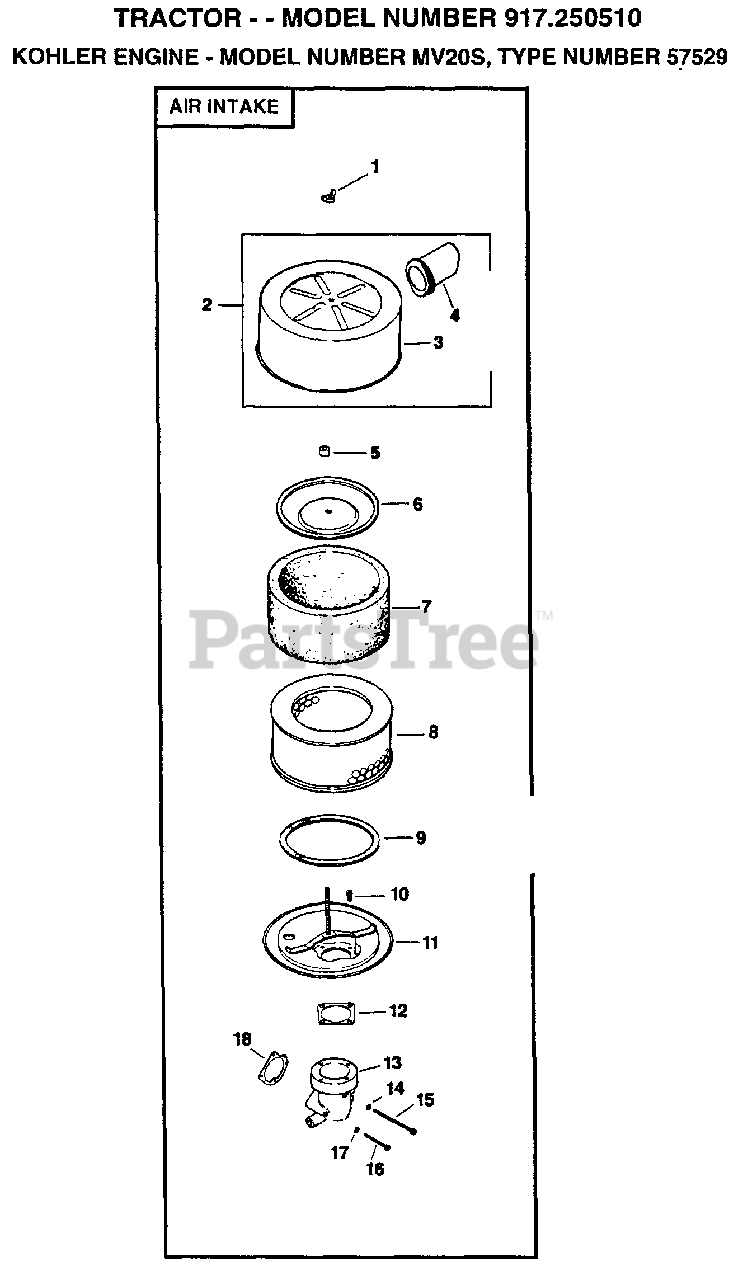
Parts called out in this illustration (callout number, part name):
1	WING NUT
3	COVER AIR CLEANER
4	TUBE, AIR INTAKE
5	SEAL ELEMENT
6	COVER AIR CLEANER ELEMENT
9	SEAL
10	SCREW
12	GASKET
13	ELBOW AIR INTAKE
14	WASHER
15	SCREW
16	SCREW
17	WASHER
18	GASKET, AIR CLEANER
